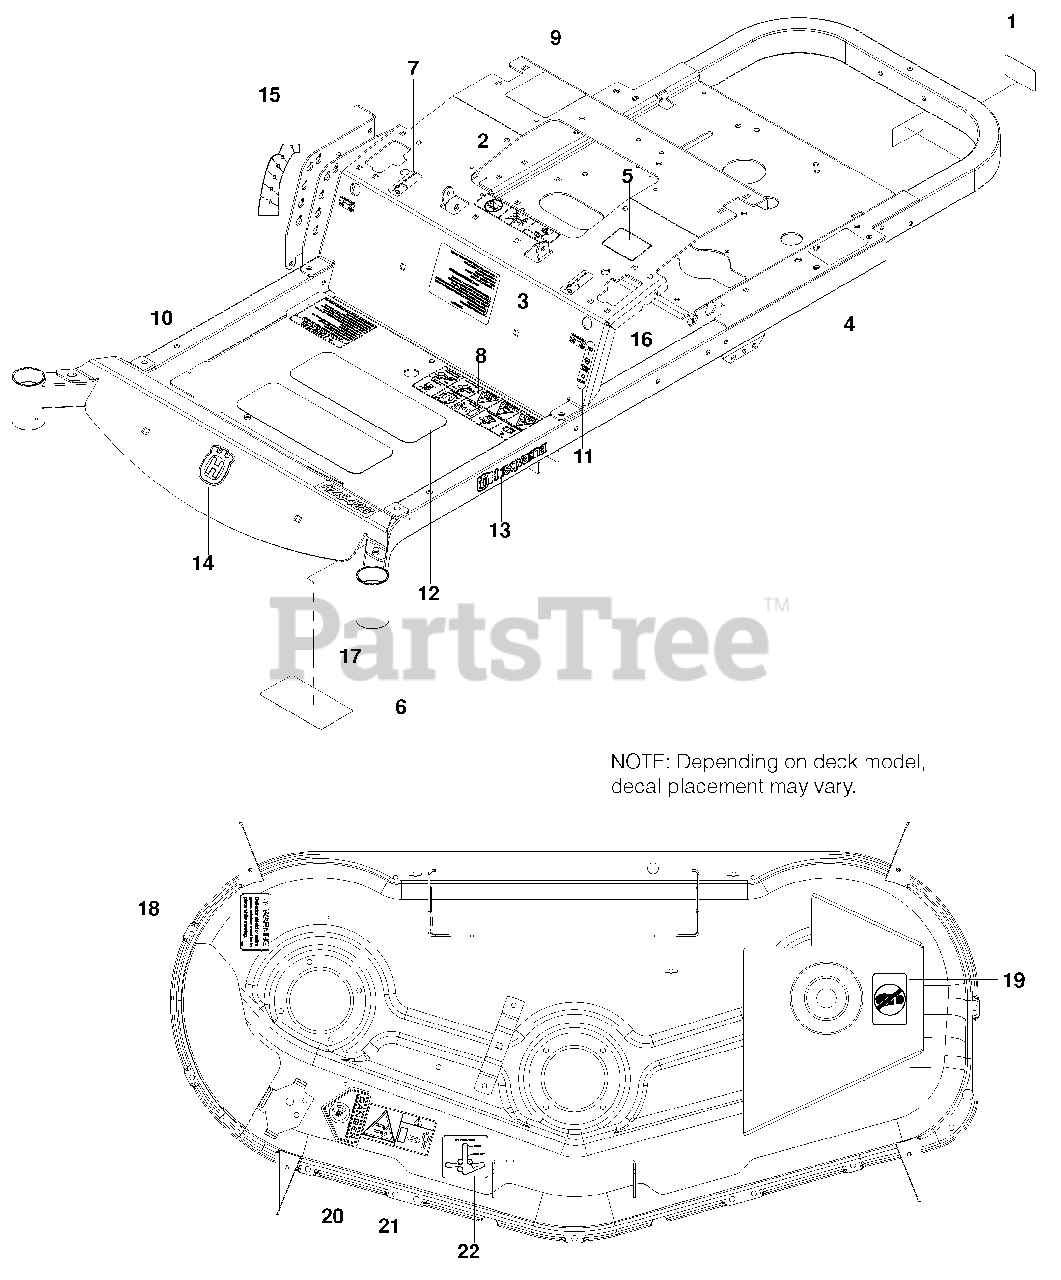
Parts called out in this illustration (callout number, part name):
1	DECAL, PROP 65
2	DECAL, BATTERY WARNING
3	DECAL, START
4	DECAL, DO NOT TOW
5	DECAL, EXIT MOWER
6	DECAL, SERVICE
7	DECAL, MOTION CONTROL
8	DECAL, SAFETY WARN
9	DECAL, RESPONSIBILITY
10	DECAL, WARNING
11	DECAL, PARK BRAKE
12	ABRASIVE PAD
13	DECAL, HUSQVARNA
14	DECAL, CROWN H
15	DECAL, HEIGHT
16	DECAL, FST
17	DECAL, RZ4219
18	DECAL, DEFLECTOR WARN
19	DECAL, NO STEP
20	DECAL, BLADES
21	DECAL, SEVERING
22	DECAL, BELT ROUTING 966495701, 965881301, 965881401
